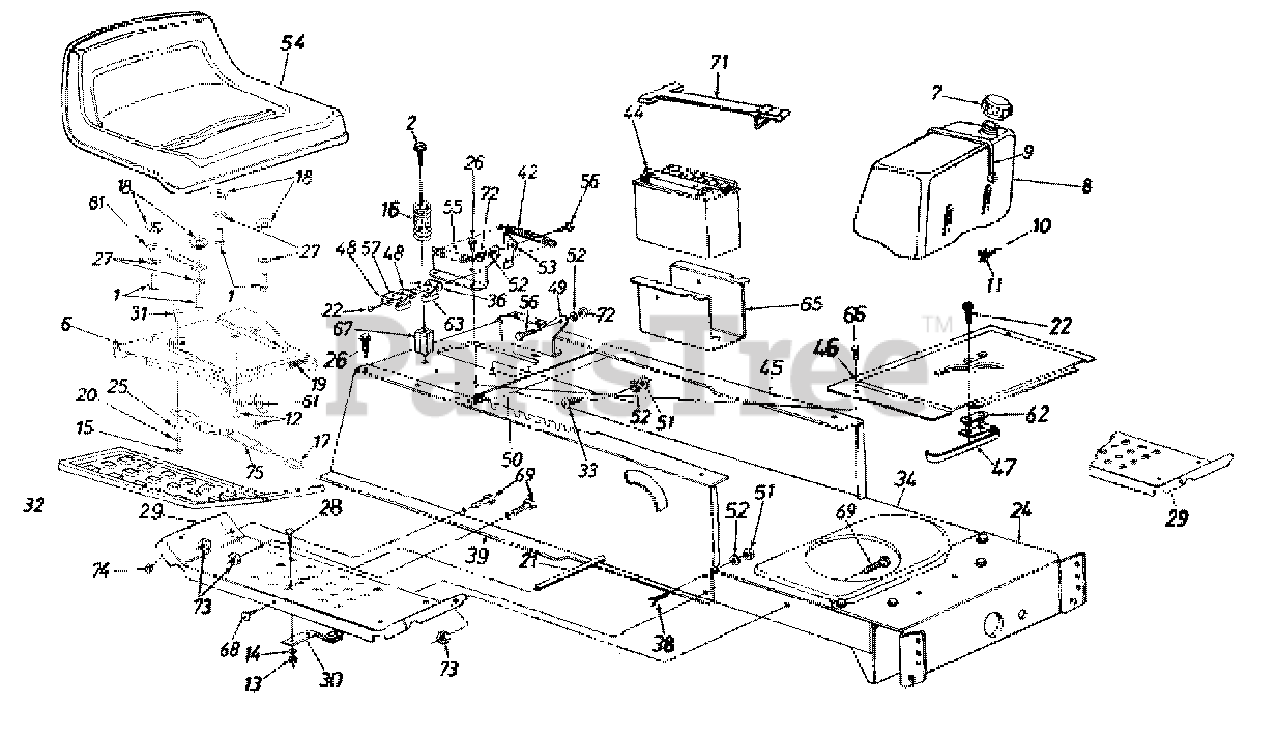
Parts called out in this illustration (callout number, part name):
1	Hex Scr. 3/8-16: 1.00
2	Hex Wash. Hd. Tap Scr. 5/16-18 x 3.25" Lg.
8	Fuel Tank (1.25 Gal.)
9	Tie Strap
10	Fuel Line
12	Hex B-Tapp Scr. #10-16 x .38
13	Hex Nut 1/4-20 Thd.
14	L-Wash. 1/4" I.D.
15	Lock Nut 1/4-20
16	Compression Spring
17	Grip
18	Seat Spacer
19	Compression Spring
20	Spr. Wash. .265 x .562 x .025
21	Running Board Rod
22	Hex Wash. Hd. AB-Tap Scr. #8 x .50" Lg.
25	Fl. Wash. .344 x .62 x .03
26	Hex Wash. Hd. AB-Tap Scr. 5/16 x .75" Lg.
27	Fl. Wash. .406 x .875 x .059
28	Carriage Bolt 1/4-20 x .75"
31	Shld. Bolt 1/4-20 Thd.
32	Rubber Foot Pad-L.H.
36	Insulator Boss Plate
38	Hex Bolt 5/16-18 x .75" Lg.
44	12-V Battery
47	Safety Switch (Reverse)
48	Insulator Plate
52	L-Wash. 5/16" I.D.
53	Seat Lift Brkt.
54	Seat-Grey
56	Shld. Bolt .437" Dia. x .268"
57	Spring Switch (Seat-Outer)
61	Seat Stop
62	Insulator Nut Plate
63	Safety Switch (Seat-Inner)
66	Tr. Mach. B-Tap Scr. #10 x .5" Lg.
67	Spring Spacer
68	Truss Mach. Scr. 5/16-18 x .75"
69	Hex Bolt 5/16-18 x .75" Lg.
71	Battery Retainer Strap
72	Hex Nut 5/16-18 Thd.
73	Hex Sems Nut 5/16-18 Thd.
74	Hex Sems Nut 1/4-20 Thd.
75	Seat Lever
